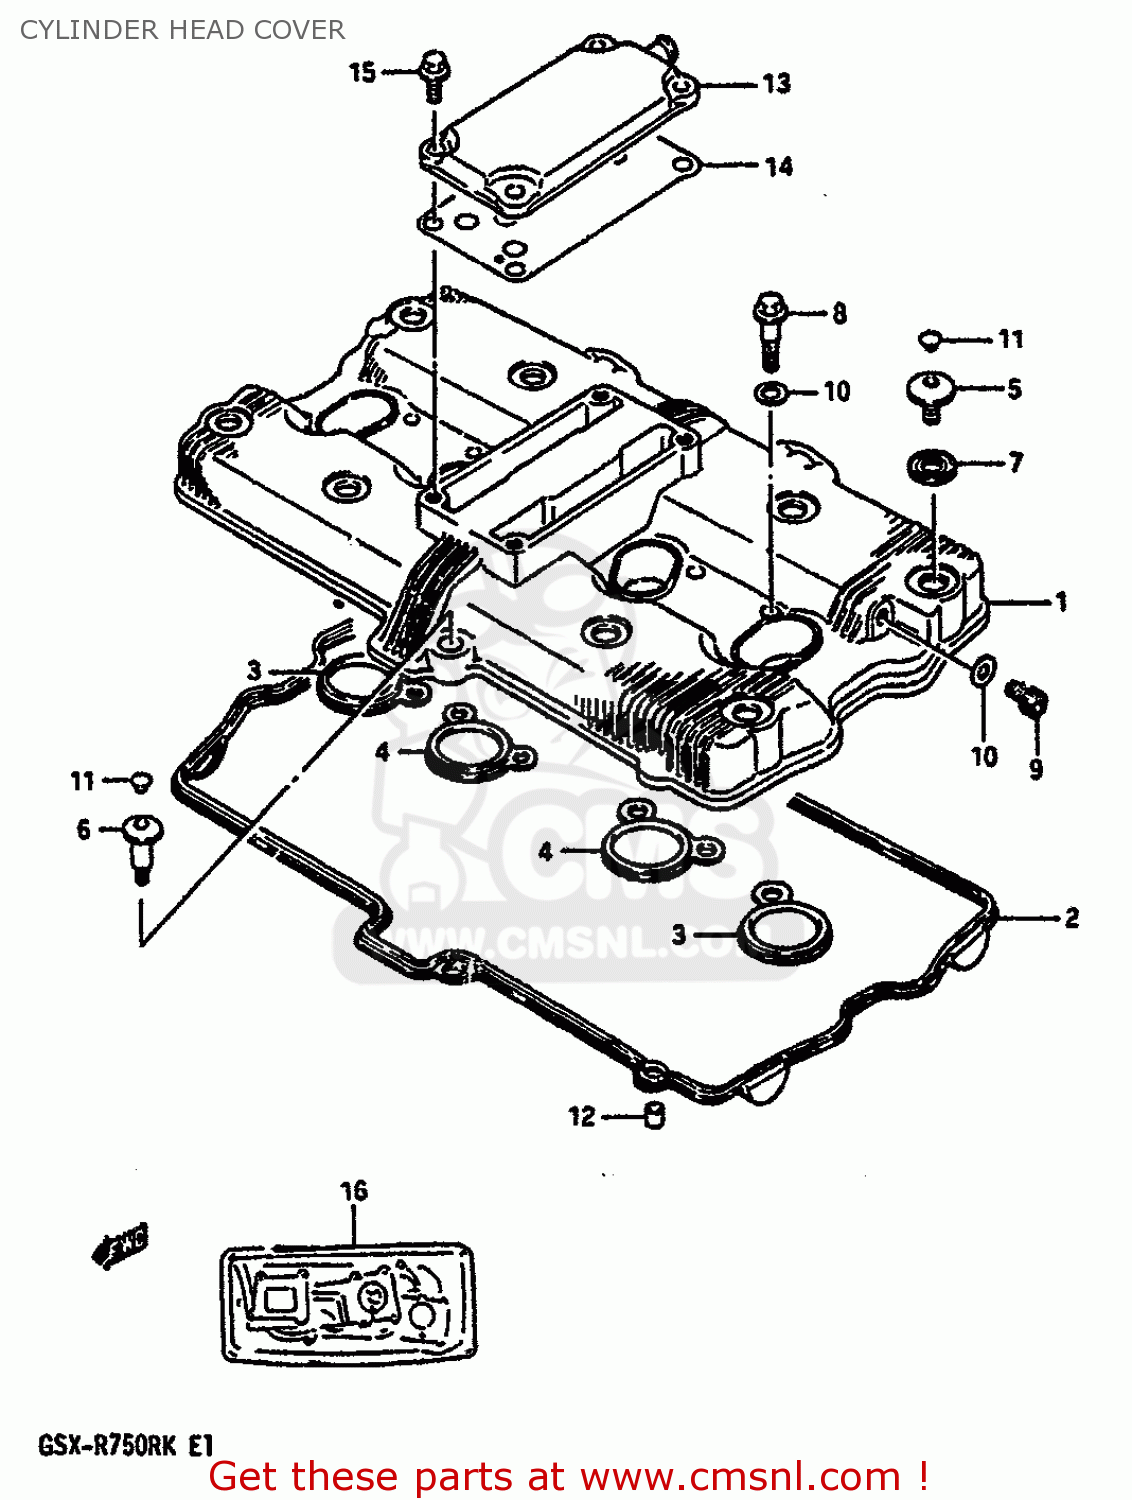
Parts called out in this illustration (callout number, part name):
1	COVER, CYLINDER
2	GASKET,CYLINDER HEAD COVER (NAS)
3	GASKET,HEAD COVER NO.2 (NAS)
4	GASKET,HEAD COVER NO.3 (NAS)
5	BOLT(7X17.5)
6	BOLT(7X31)
7	WASHER
8	BOLT,UNION 8X35
9	PLUG, HEAD COVER
10	GASKET 8.2X14X1 (NAS)
11	CAP(OD:10)
12	PIN
13	COVER,BREATHER
14	GASKET (NAS)
15	BOLT
16	GASKET SET
